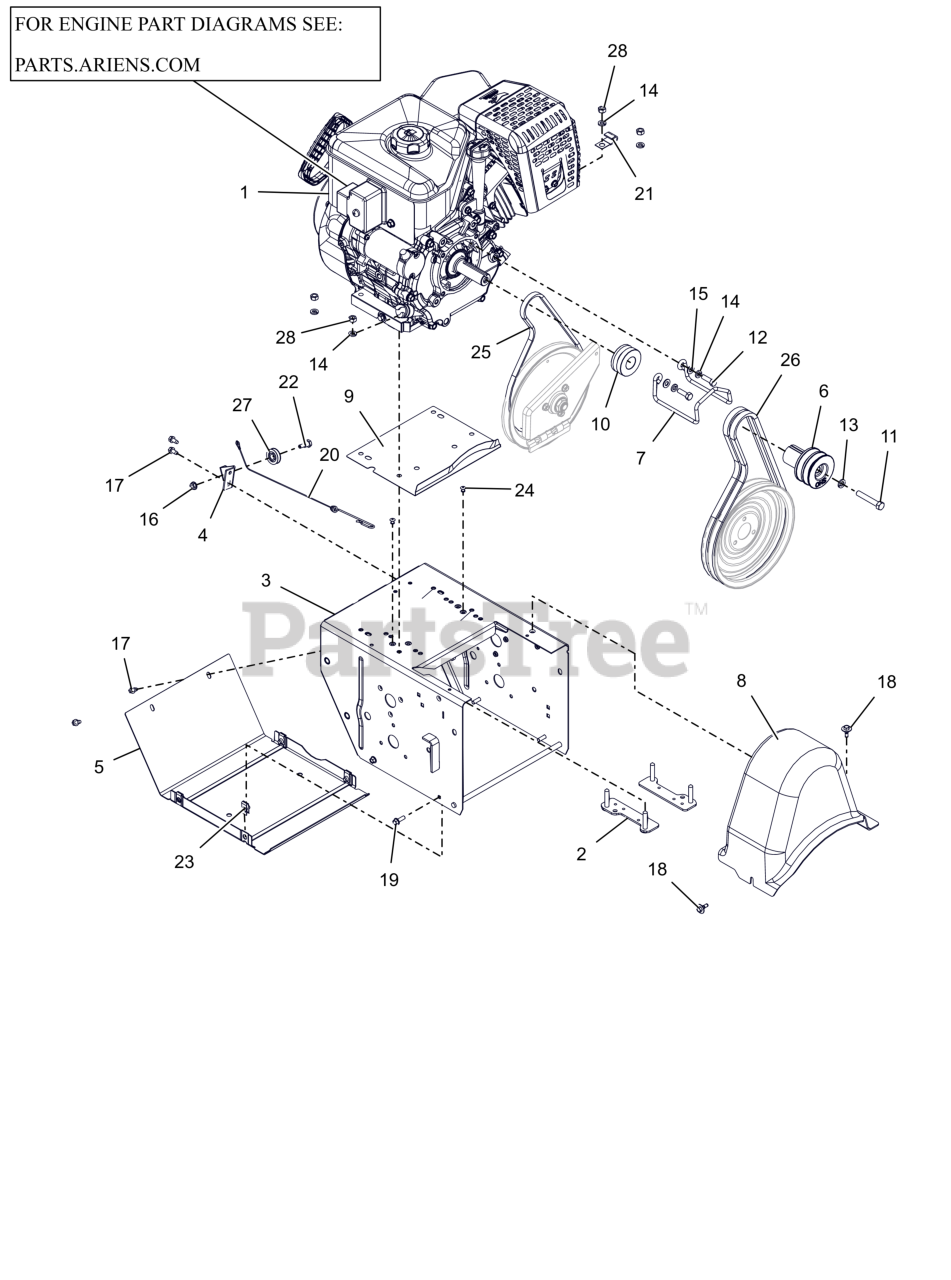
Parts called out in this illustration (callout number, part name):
1	ENGINE,EFI369 GEN3 120V/60W
2	STRAP, BOLT-LARGE
3	FRAME, MAIN - 14GA DELUXE (ORANGE)
4	BRACKET, CABLE PULLEY
5	COVER, BOTTOM
6	SHEAVE,ATTACHMENT-SHO 2 GRV
7	FINGER, BELT
8	COVER, BELT-LARGE
9	BAFFLE, WATER - LARGE BLOCK
10	SHEAVE, TRACTION (KEYLESS)
11	BLT, HEX .38-24X2.25 G5 ZCC
12	BLT, HEX 0.3125-24X1 G5 ZCC
13	WSHR,LK-REG .375X.094 ZCC
14	WSHR, LK-HVY .312X.097 ZCC
15	WSHR,FLT .344X.688X.065 ZCC
16	NUT-LK-TOP-FLG .250-20 GF ZCC
17	SCR-TAP .25-20X.50 HWH ZCC
18	SCR-TAP .25-20X.5 CAPTIVE
19	BLT, HWH .25-20X.75 G5 ZCC
20	CABLE, LOWER TRACTION,SS & PRO
21	J-CLAMP
22	BOLT, SHLDR -.375 X .375 X .25-20
23	NUT-RTNR .25-20X.56
24	RVT, POP .1875 ZCC
25	V-BELT, 3L-WRAPPED
26	V-BELT, HA-RAW EDGE (SET)
27	PULLEY, CABLE
28	NUT, HEX .312-18 ZCC
